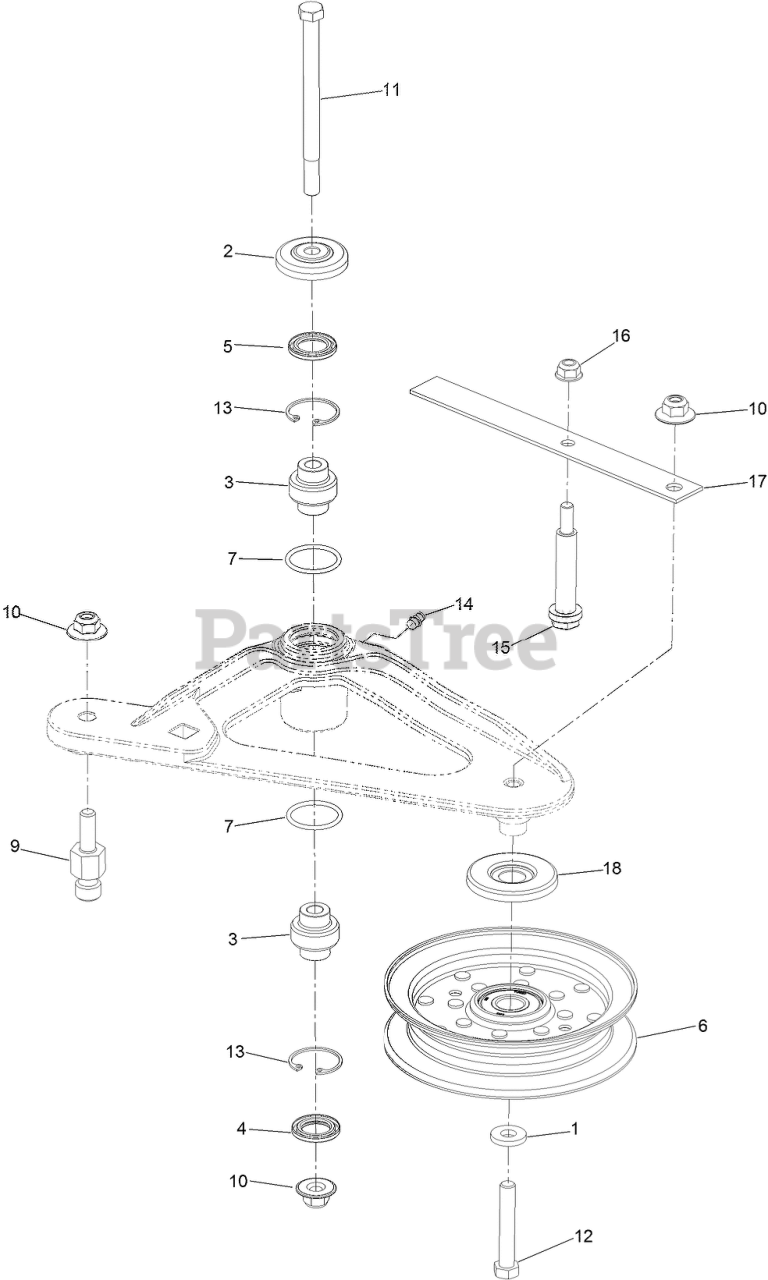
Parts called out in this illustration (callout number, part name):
2	GUARD-TOP
3	BEARING-SPHERICAL
4	SEAL-LIP, DOUBLE
5	SEAL-LIP, SINGLE
6	IDLER-PULLEY, FLAT
9	PIN-SPRING, ANCHOR
10	Nut-Nyloc 3/8-16 Flg
11	SCREW-SHOULDER, HH
12	SCREW-HH
13	RING-SNAP
14	FITTING-GREASE
15	BOLT-SHOULDER
16	NUT-HF, NI
17	SPRING-BELT
18	SHIELD-GUARD, DUST
